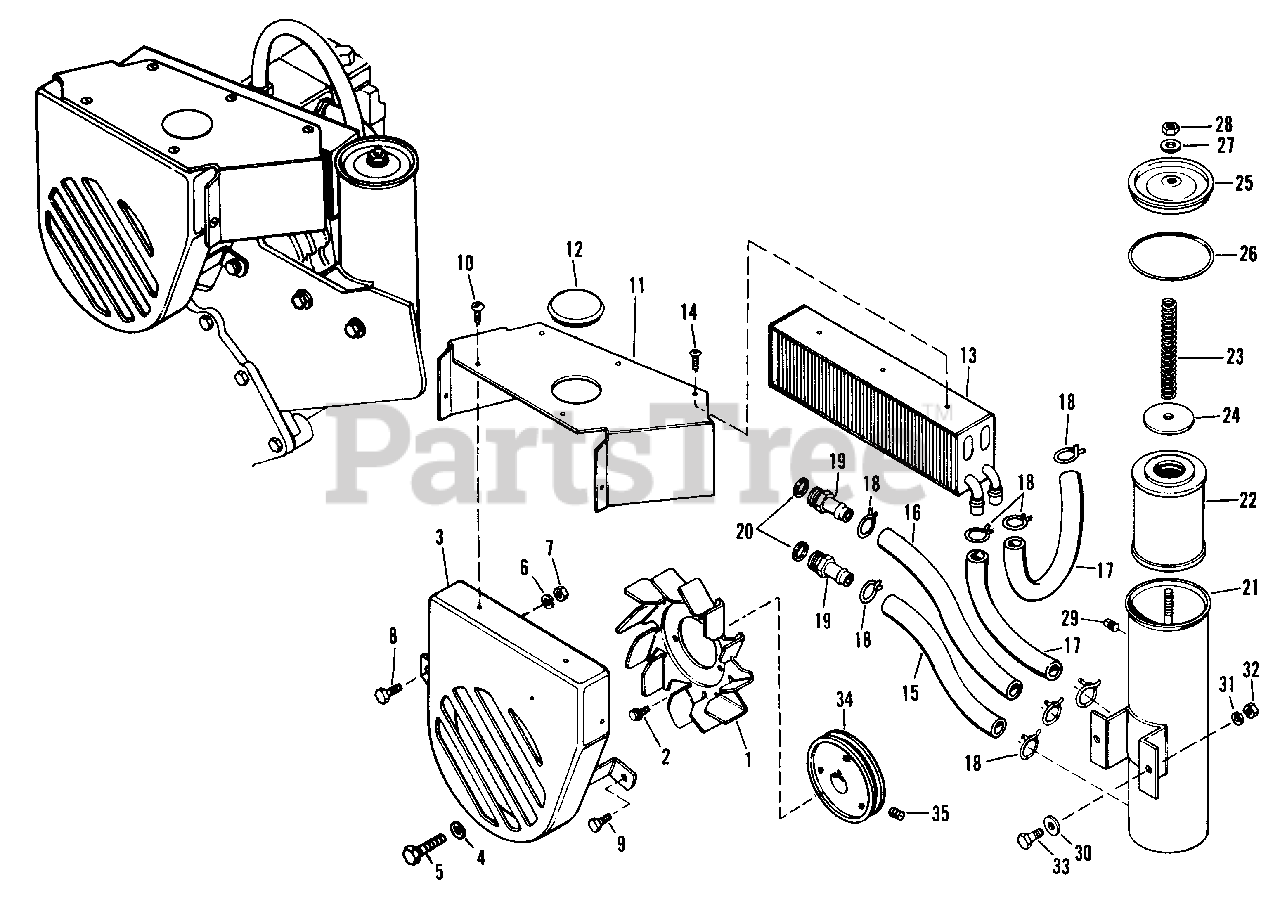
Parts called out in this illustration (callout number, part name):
2	Hex Screw, Washer Hd.
3	Fan Shroud Assy.
4	Lock Washer
5	Hex Cap Screw, 3/8"-16 x 2"
6	Lock Washer, 5/16"
7	Full Hex Nut, 5/16"
8	Hex Capscrew, 5/16"-18 x 3/4"
9	Hex Screw, Thd.
10	Self Tapping Screw, No. 10 x 3/8"
11	Cooler Deflector
13	Oil Cooler
14	Rd. Hd. Mach. Screw, No. 10-32 x 1/2"
15	Hydraulic Hose
16	Hydraulic Hose
17	Hydraulic Hose
18	Hose Clamp
19	Beaded Insert
21	Reservoir Assy.
22	Filter Element
25	Reservoir Cover
27	Nylon Washer
28	Elastic Stop Nut
29	Pipe Plug, 1/4"
30	Plain Washer, 5/16"
31	Lock Washer, 5/16"
32	Full Hex Nut, 5/16"-18"
33	Hex Capscrew, 5/16"-18 x 3/4"
34	Driven Pulley
35	Cup Pt. Socket Hd. Set Screw, 5/16"-18 x 5/16"
